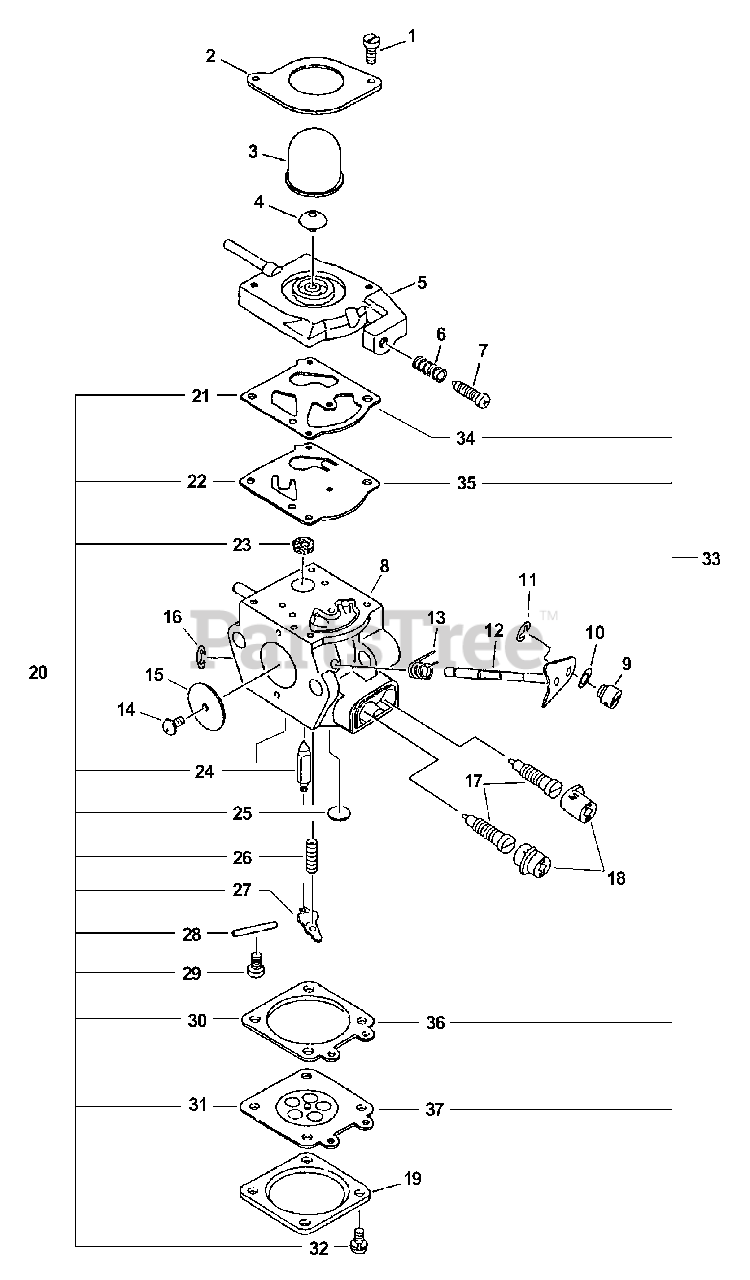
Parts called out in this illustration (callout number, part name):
1	SCREW, PUMP COVER
2	RETAINER, PURGE BULB
3	BULB, PURGE
4	VALVE, CHECK
5	BASE, PURGE
6	SPRING, IDLE ADJUST
7	SCREW, IDLE ADJUST
8	BODY, CARBURETOR
11	RING, RETAINING
12	SHAFT, THROTTLE
13	SPRING, THROTTLE RETURN
15	VALVE, THROTTLE
16	RING, RETAINING
17	NEEDLE - MIXTURE
18	CAP, LIMITER
19	COVER, METERING
20	REPAIR KIT
21	GASKET, PUMP
22	DIAPHRAGM, PUMP
23	STRAINER
24	VALVE, INLET NEEDLE
25	PLUG, WELCH
26	SPRING, METERING LEVER
27	LEVER, METERING
28	PIN, METERING LEVER
29	SCREW, METERING LEVER PIN
30	GASKET, METERING
31	DIAPHRAGM, METERING
32	SCREW, DIAPHRAGM COVER
33	DIAPHRAGM/GASKET KIT
34	GASKET, PUMP
35	DIAPHRAGM, PUMP
36	GASKET, METERING
37	DIAPHRAGM, METERING
